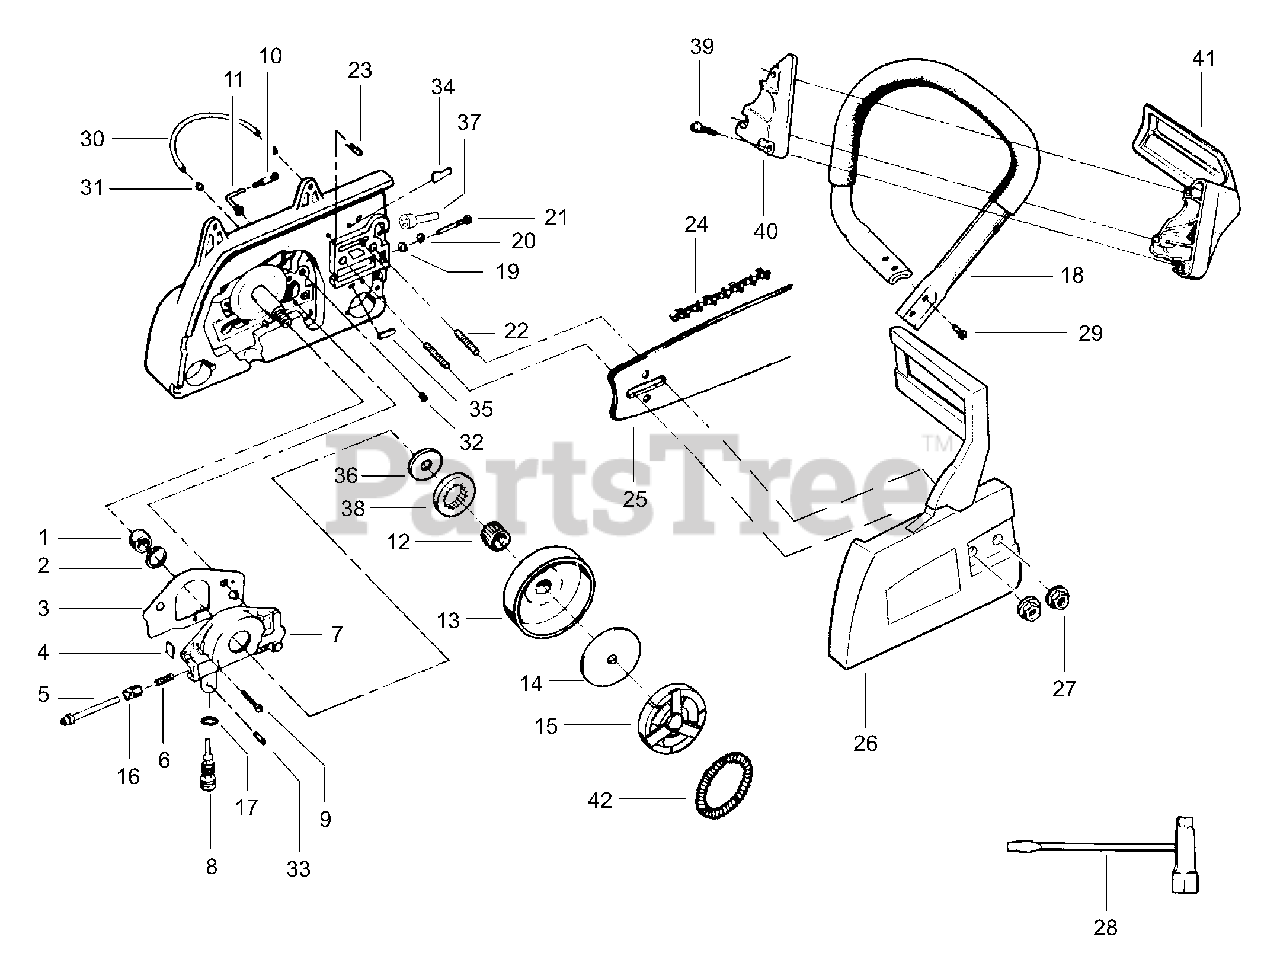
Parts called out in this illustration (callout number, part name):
1	Worm Gear
3	Gasket Kit
4	Dust Plug
7	Oil Pump Ass'y.
8	Oiler Adjustment Screw
9	Screw
10	Oil Pickup & Filter
11	Oiler Intake Line
12	Clutch Bearing
13	Drum Sprocket
14	Clutch Plate
15	Clutch Ass'y. Model 3450 T1 & T2 & T4
15	Clutch Ass'y. Model 3750 T1 & T2, 3450 T3
16	Oiler Gear Spur
17	"O" Ring
18	Handlebar Ass'y.
19	Bar Adjusting Pin
20	Retainer
22	Bar Stud
23	Vent Pin
24	Chain Model 3450-20" (72LXP)
24	Chain Model 3750-22" (72LXP)
25	Bar Model 3450-20" (SN)
25	Bar Model 3750-22" (SN)
26	Chainbrake (Type 4)
28	Scrench Silver finish (1/2" x 3/4")
28	Scrench Gold finish (9/16" x 3/4")
30	Oiler Discharge Line
31	Oiler Discharge Sleeve
32	Tubing Nut
33	Oiler Adjustment Pin
34	Chain Pad- Top
35	Chain Pad
36	Thrust Washer
37	Crankcase Plug
38	Rim Floating (3/8)
39	Screw-Handguard (Type 1-3 only
40	Cap-Handguard (Type 1-3 only)
41	Handguard (Type 1-3 only)
42	Spring- Clutch
